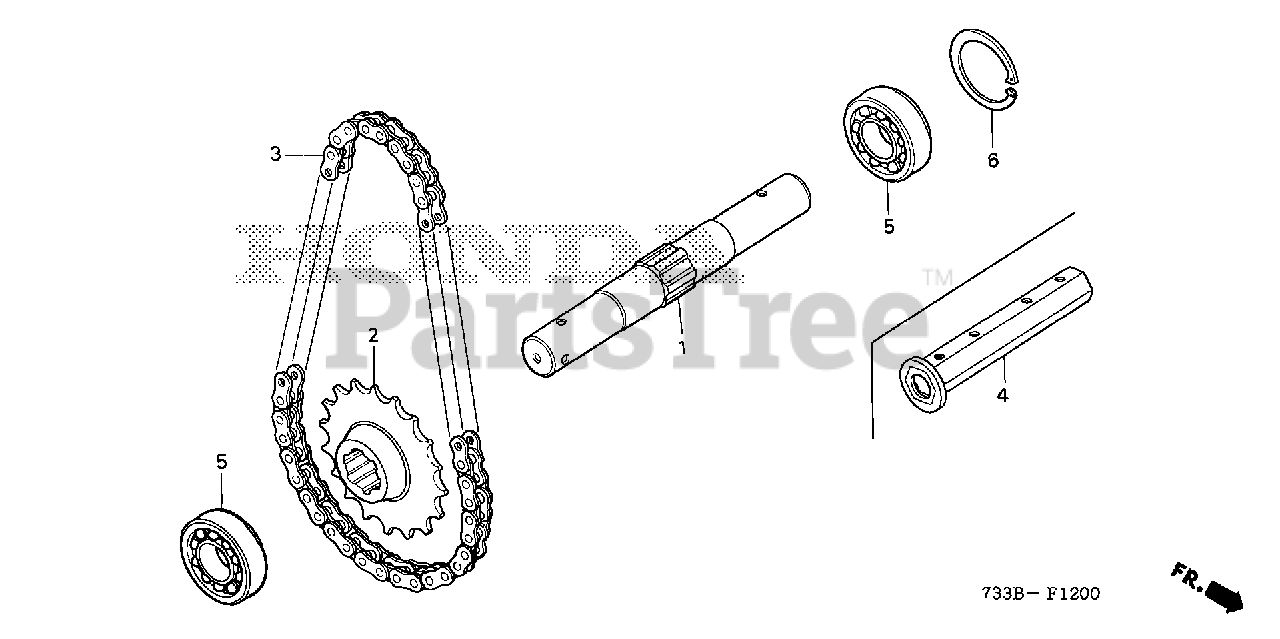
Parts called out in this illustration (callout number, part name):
1	SHAFT, WHEEL
2	SPROCKET, DRIVEN (18T)
3	CHAIN, FINAL (RK520KFX44LE)
4	SHAFT A, EXTENSION (23X32X179)
5	BEARING, RADIAL BALL (60/32)
6	CIRCLIP (INNER) (58MM)
